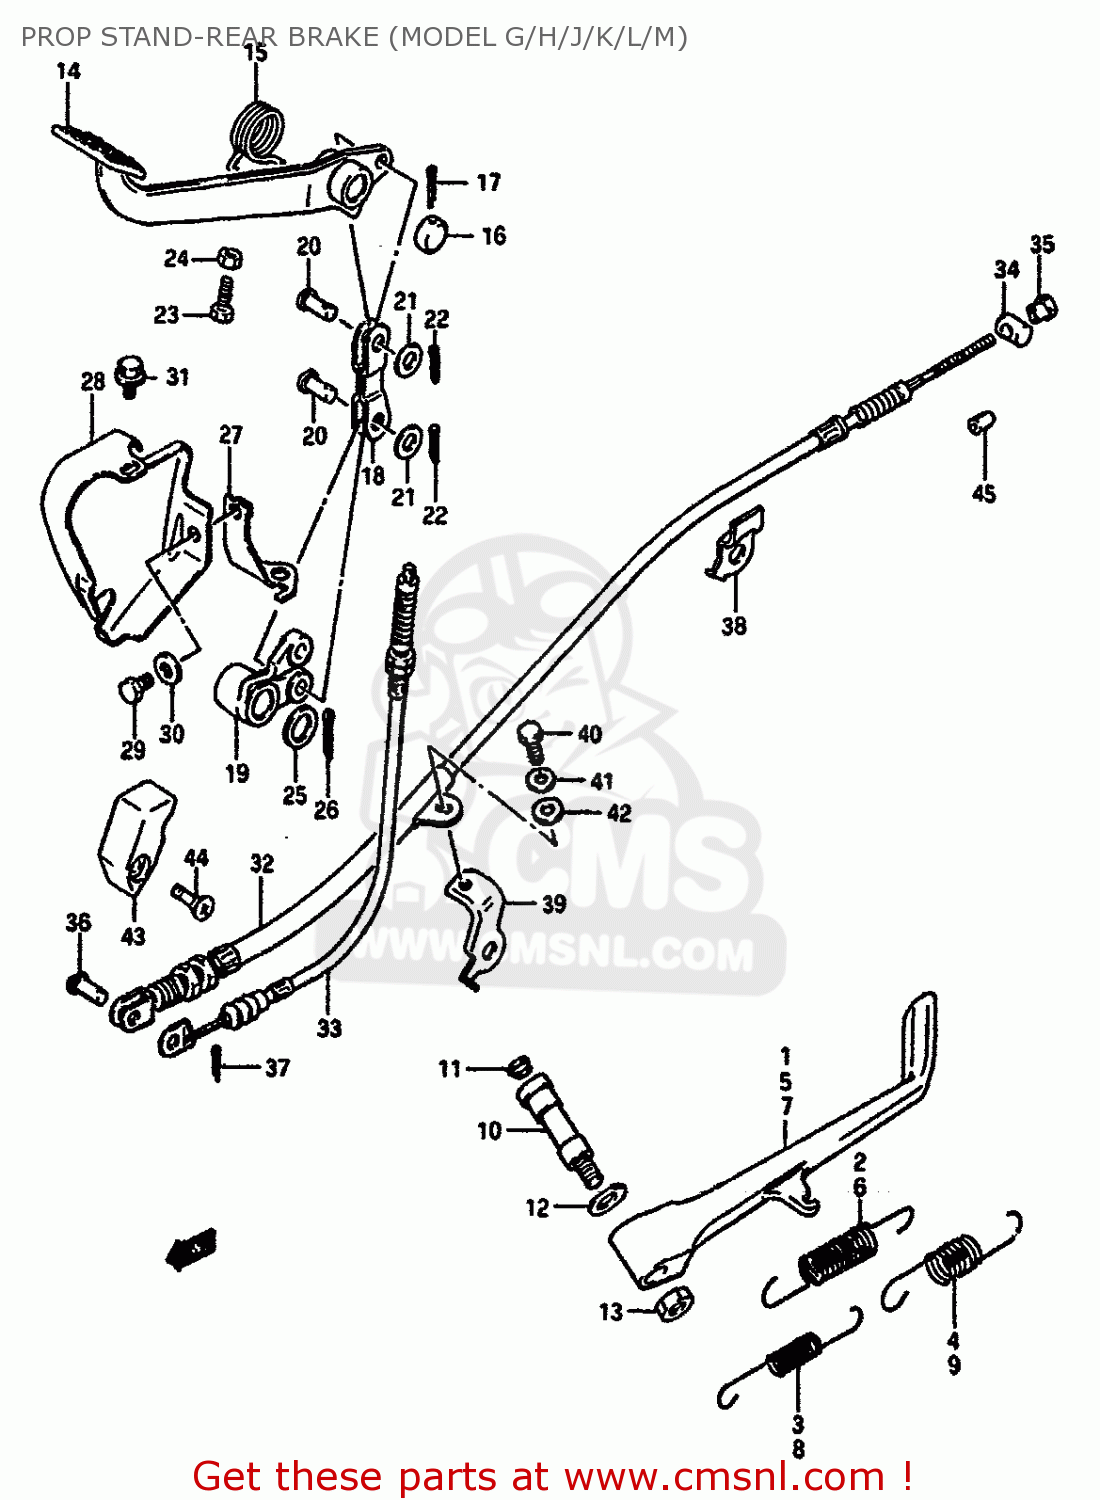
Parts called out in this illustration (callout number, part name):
1	STAND,PROP
2	SPRING
3	SPRING,INNER
4	SPRING,OUTER
5	STAND,PROP
6	SPRING
7	STAND,PROP
8	SPRING
9	SPRING
10	BOLT,PROP STAND
11	CAP
12	THRUST WASHER
13	NUT
14	PEDAL,BRAKE
15	SPRING
16	CAP,BRAKE PEDAL
17	COTTER PIN
18	LINK COMP,BRAKE ROD NO
19	ARM,BRAKE PEDAL LINK
20	PIN
21	WASHER
22	PIN
23	BOLT
24	NUT 6MM
25	WASHER (16.5X42X2.6)
26	COTTER PIN
27	BRACKET COMP,BRAKE COVER
28	COVER,BRAKE
29	SCREW(6X10)
30	WASHER(6.5X15X1.0)
31	BOLT
32	CABLE ASSEMBLY,REAR BRAKE
33	CABLE,STOP LAMP SWITCH
34	PIN
35	NUT (6MM)
36	PIN(L:17.5)
37	PIN
38	CLAMP,RR BRAKE CABLE
39	BRACKET,RR BRAKE CABLE
40	BOLT
41	WASHER,LOCK
42	WASHER 6MM
43	GUIDE,RR BRAKE CABLE
44	SCREW
45	CAP,GREASE NIPPLE
